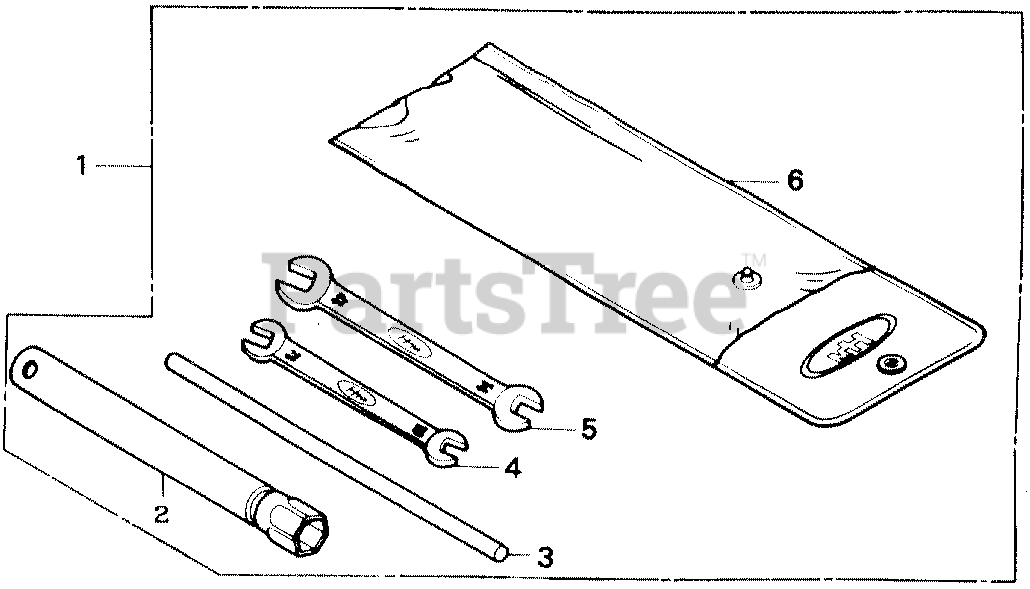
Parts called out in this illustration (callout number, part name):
1	TOOL KIT (NOT AVAILABLE)
2	WRENCH, SPARK PLUG
3	HANDLE, BOX WRENCH
4	SPANNER (10X12)
5	SPANNER (14X17)
